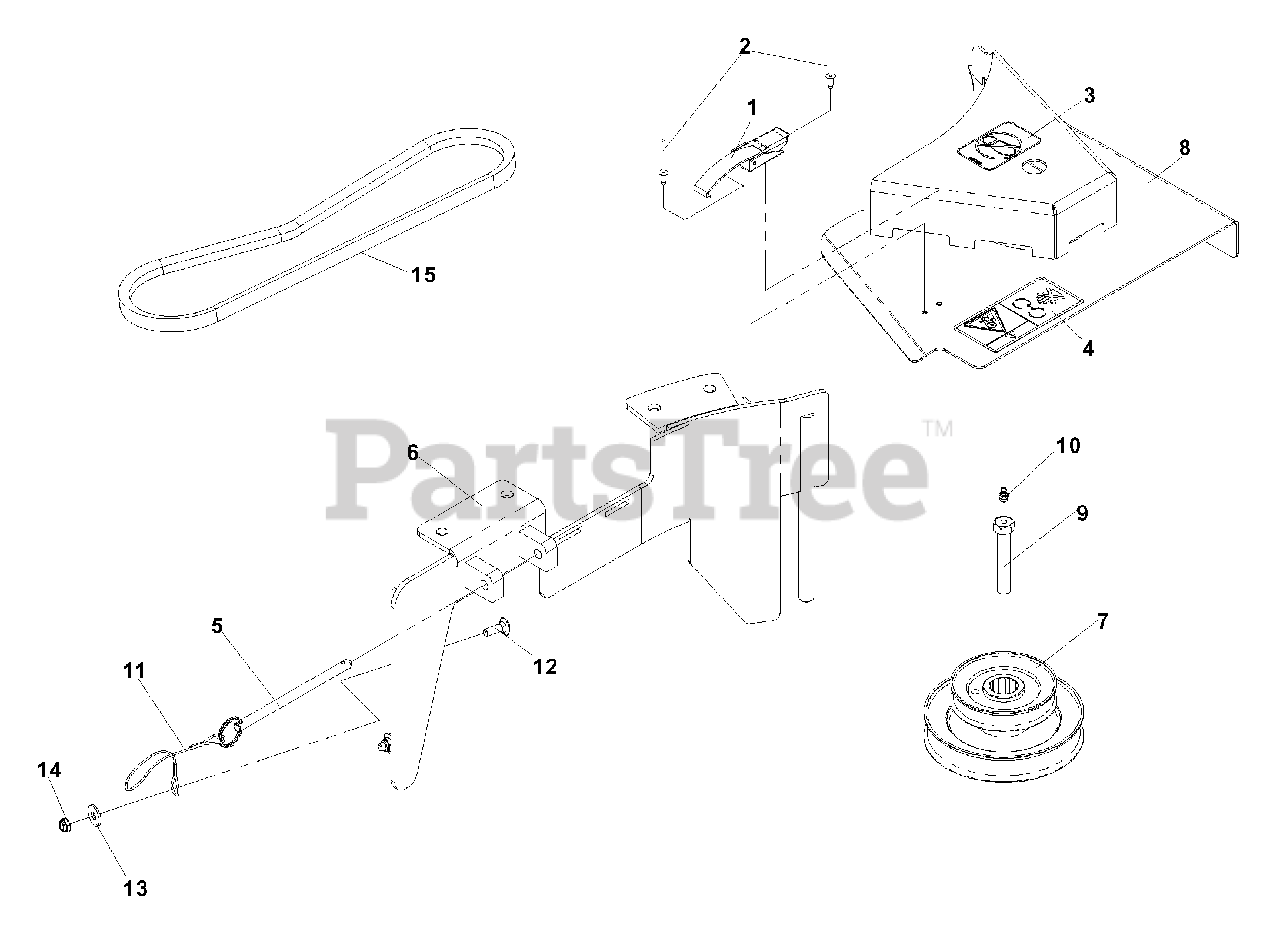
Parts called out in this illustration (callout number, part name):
1	DRAW LATCH
2	RIVET, BLIND, DOME
3	DECAL, NO STEP
4	DECAL, BELT DRIVES
6	BLOWER DECK PLATE, 52
7	PULLEY, STACKED DBL, 52
8	BELT SHIELD W/DECALS
9	HCS, 7/16 -20 x 2 1/2, GR8
10	ZERK
12	RHSNB, 1/4 -20 x 3/4, GR2
13	WASHER, 1/4
14	NUT, 1/4C, THIN NYLOC
